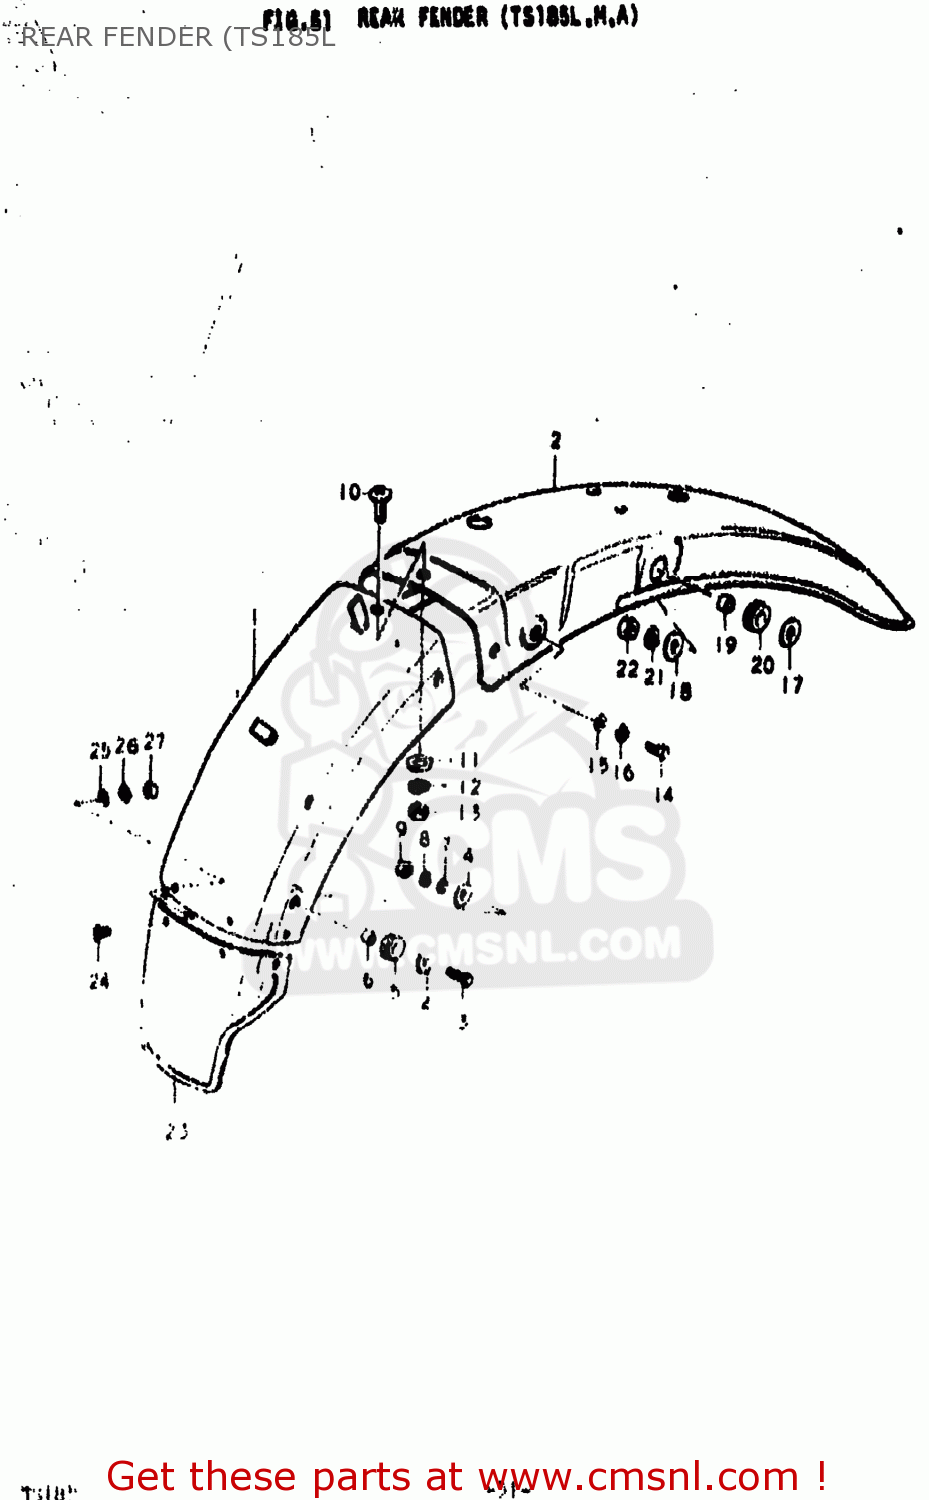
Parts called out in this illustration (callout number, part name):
1	FENDER,REAR
2	FENDER,REAR
3	BOLT
4	WASHER (6.5X20X1.2)
5	CUSHION
6	SPACER(6.1X9X7.5)
7	WASHER
8	LOCK WASHER
9	NUT
10	SCREW
11	WASHER
12	LOCK WASHER
13	NUT
14	BOLT
15	WASHER
16	LOCK WASHER
17	WASHER(10.3X25X1.5
18	WASHER(10.3X25X1.5
19	SPACER
20	CUSHION
21	LOCK WASHER
22	NUT
23	MUD GUARD,REAR FENDER
24	SCREW
25	WASHER(5.2X16X1)
26	LOCK WASHER
27	NUT
